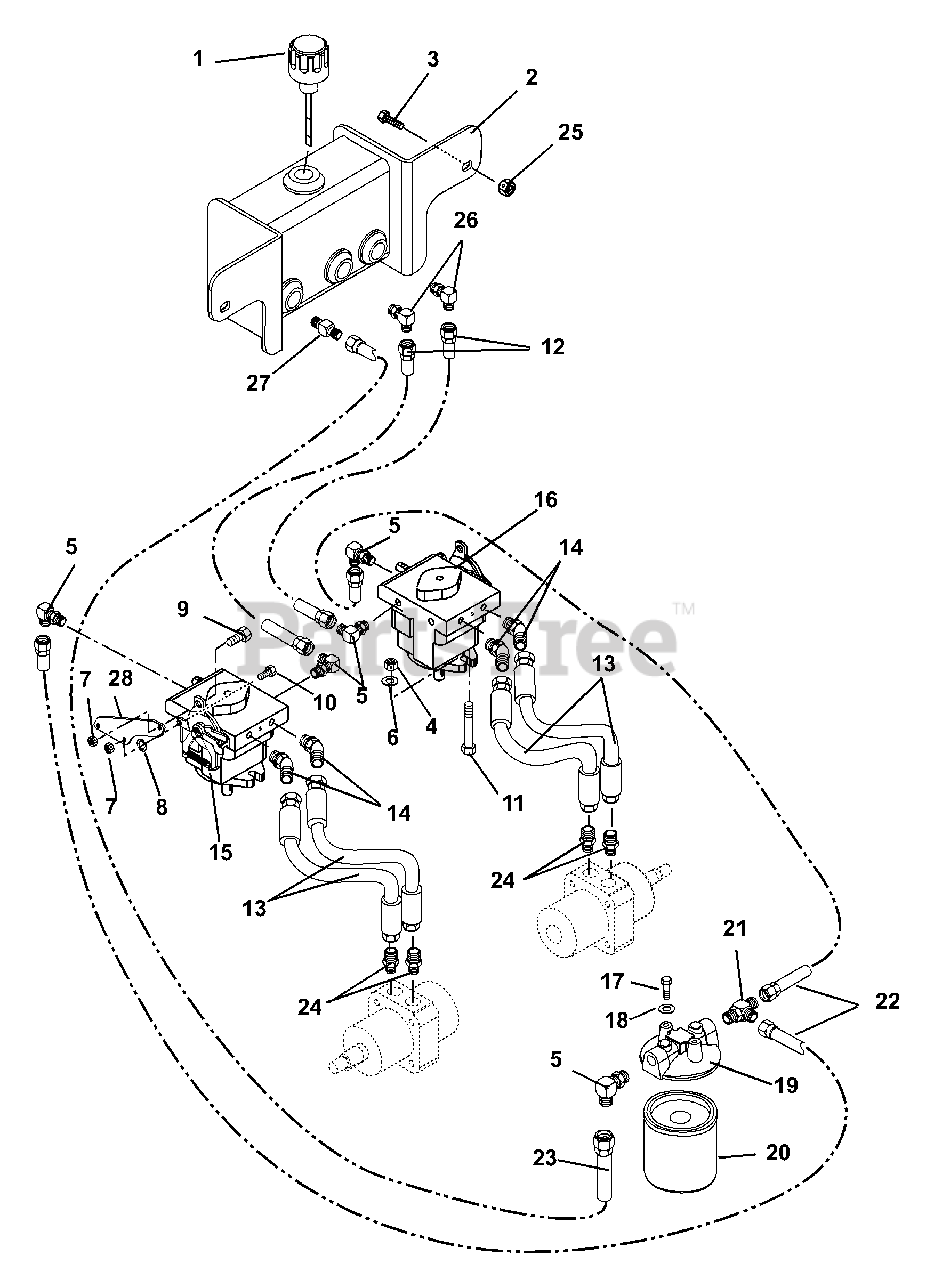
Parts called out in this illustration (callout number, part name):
1	BREATHER, DIPSTICK
2	WMT - TANK - HYDRAULIC
3	@BLT-HEX .38-16X1.00 GR5 YWZC
4	@NUT-LK-NYL .44-14 YWZC
5	FITTING, HYD (6 C5OLO)
6	WSHR,FLT .438X1.00X.160 ZCC
7	@NUT-LK-CTR .31-18 YWZC
8	BSHG-SLV .377X.624X.370
9	@BLT-HEX .31-18X1.00 GR5 YWZC
10	@BLT-HEX .31-18X.50 GR5 YWZC
11	@BLT-HEX .44-14X1.50 GR5 YWZC
12	HOSE HYD .37-10-0K F06F0-F06F0
13	HOSE,HYD .5-22-2K F08F0-F08F0
14	FTG,HYD 45DEG M8F-M80
15	PUMP, HYD. RH W/RTN
16	PUMP, HYD. LH W/RTN
17	@BLT-HEX .25-20X.50 GR5 YWZC
18	@WSHR-LK .25X.062 REG YWZC
19	HEAD, FILTER
20	ELEMENT, FILTER BE-40-0
21	FTG,HYD TEE M6F-M6F-M60
22	HOSE,HYD .37-22-0K F06F0-F06F0
23	HOSE HYD .37-13-0K F06F0-F06F9
24	FTG, HYD STR M10O-M8F
25	@NUT-LK-NYL .38-16 YWZC
26	FTG, HYD ELBOW M6F-M8O
27	FTG, HYD STR M8O-M6F
28	BRACKET, RTN/DAMPER
